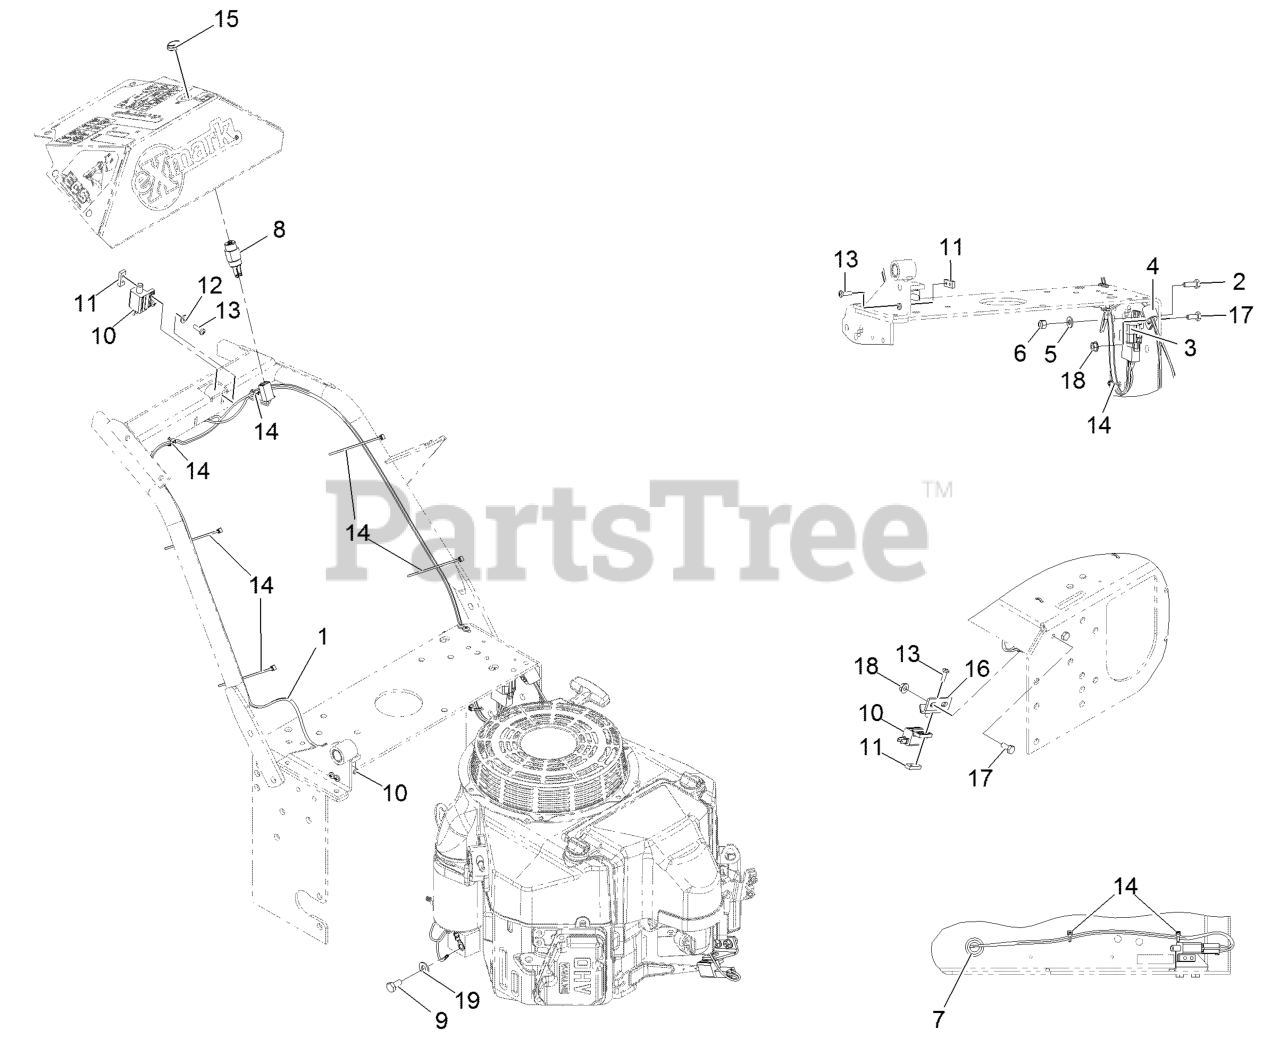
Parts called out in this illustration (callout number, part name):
1	HARNESS-WIRING
2	SCREW-HH
3	MODULE-INTERLOCK
4	CLIP-LOOM
5	WASHER-FLAT
6	NUT-LOCK, NI
7	GROMMET
8	SWITCH & KEY (INCLUDES NU
9	SCREW-HH
10	SWITCH-OPEN, NORMALLY
11	PLATE-TAPPED
12	WASHER-FLAT
13	SCREW-PPH
14	TIE-CABLE
15	NUT-SWITCH, IGNITION
16	BRACKET-SWITCH, BLADE
17	SCREW-HH
19	WASHER-PLAIN
